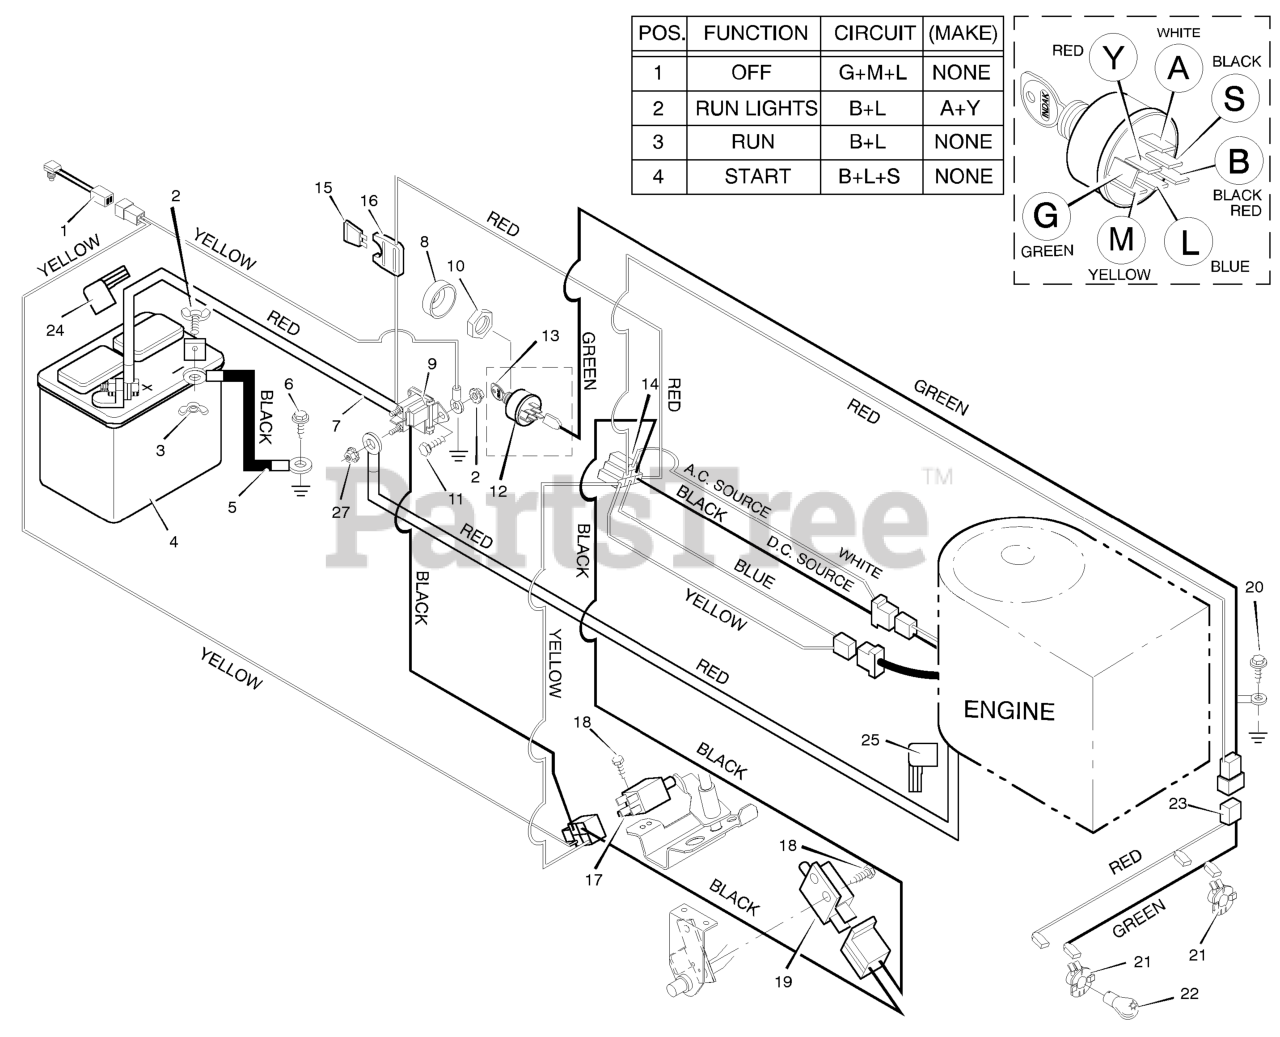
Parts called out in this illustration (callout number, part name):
1	Switch, Seat Sensor
3	Wingnut
4	Battery
5	Cable, Battery Ground
7	Cable, Red Battery
8	Cap, Ignition
9	Solenoid
10	Nut
12	Switch, Ignition
13	Key, Ignition
14	Harness, Chassis Wire
16	Holder, Fuse
19	Switch, Clutch
20	Screw
21	Socket, Light
22	Bulb, Light
23	Harness, Light Wire
24	Cover, Terminal
25	Cover,
27	Locknut
